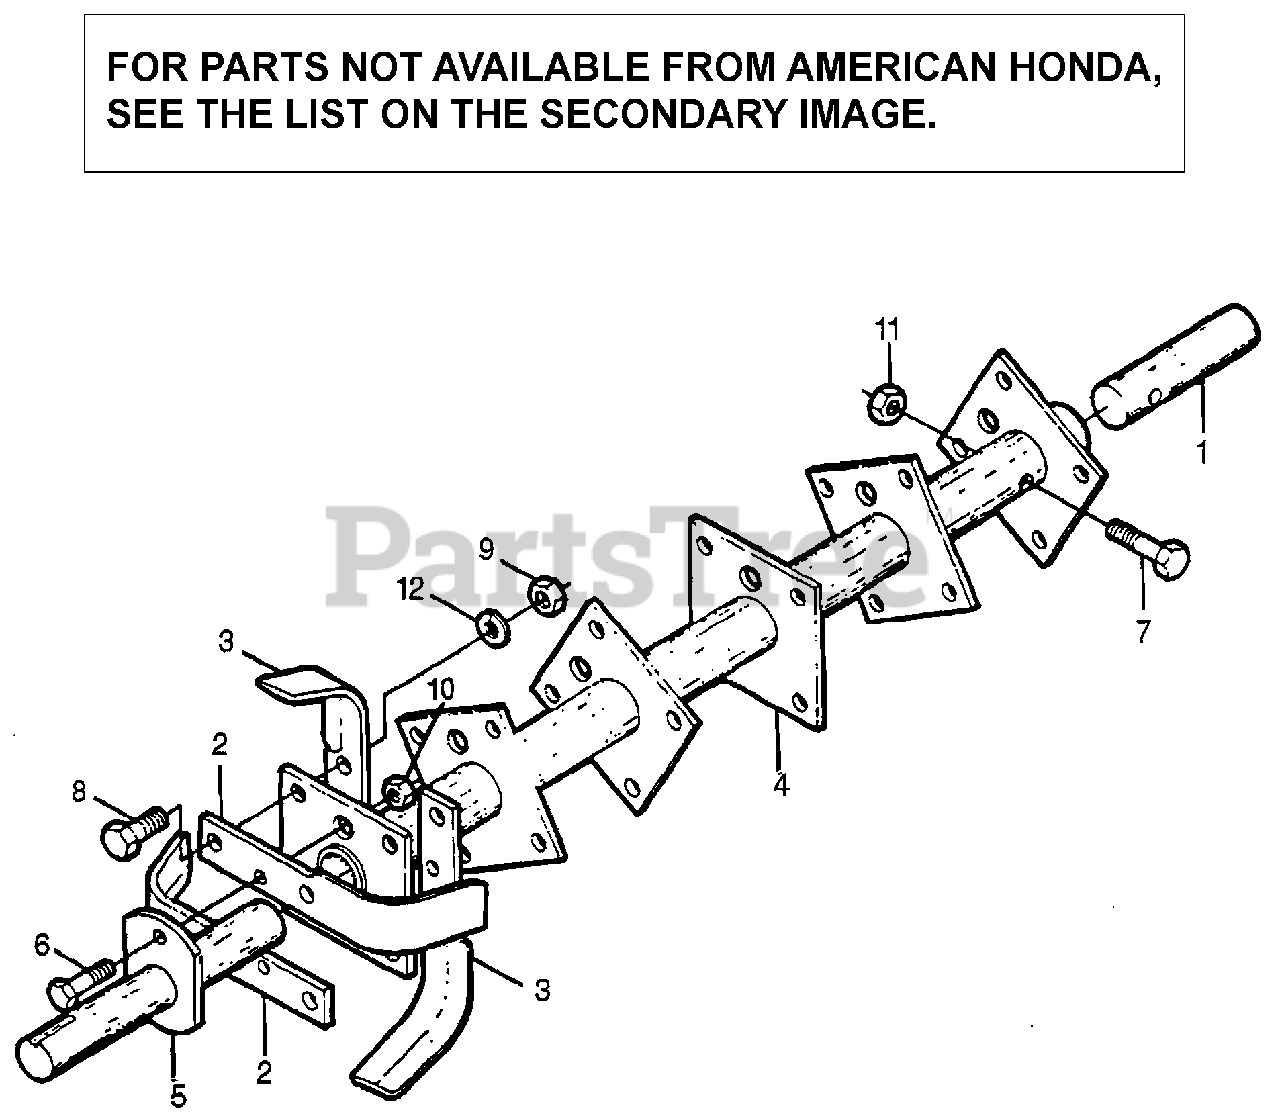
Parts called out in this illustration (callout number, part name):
2	TINES, R. (NOT AVAILABLE)
3	TINES, L. (NOT AVAILABLE)
4	WELDMENT, ROTOR
5	WELDMENT, STUB SHAFT (NOT AVAILABLE)
8	SCREW, CAP (7/16X1-1/2") (NOT AVAILABLE)
9	NUT, HEX. (7/16"X14) (UNC GR. 5) (NOT AVAILABLE)
10	NUT, LOCK (5/16") (18 UNC)
12	WASHER, LOCK (7/16") (NOT AVAILABLE)
